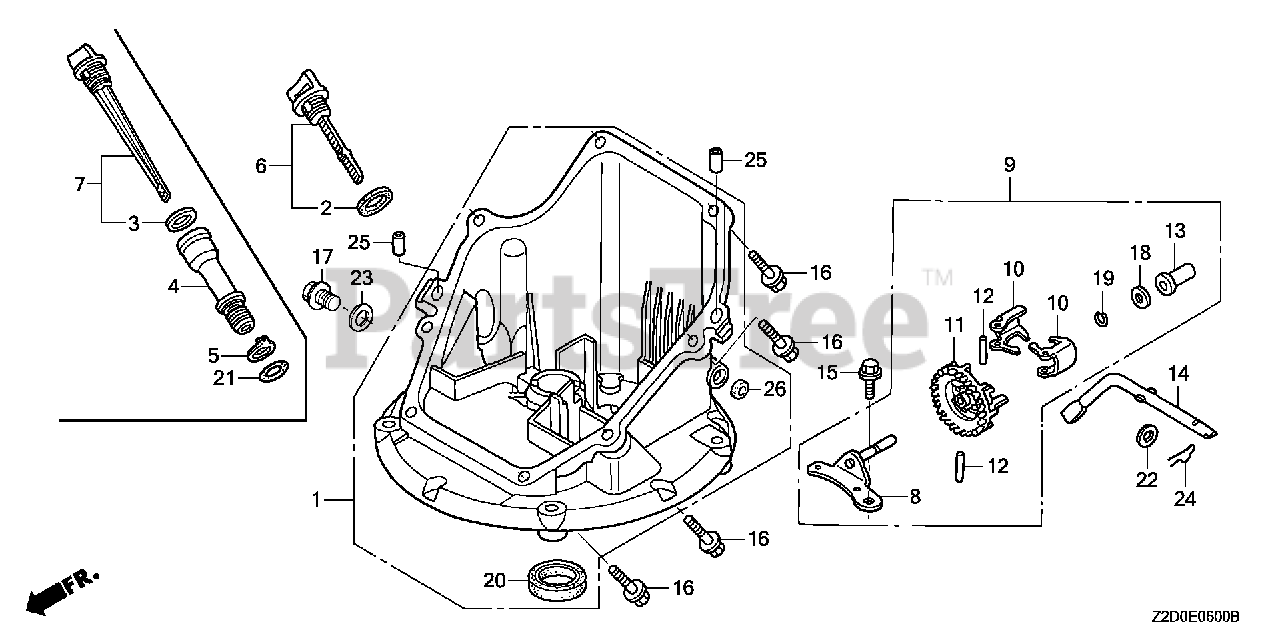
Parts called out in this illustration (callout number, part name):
1	PAN ASSY., OIL
2	GASKET, OIL FILLER CAP
6	GAUGE ASSY., OIL LEVEL
8	SHAFT, GOVERNOR HOLDER
9	GOVERNOR ASSY.
10	WEIGHT, GOVERNOR
11	HOLDER, GOVERNOR WEIGHT
12	PIN, GOVERNOR WEIGHT
13	SLIDER, GOVERNOR
14	SHAFT, GOVERNOR ARM
15	BOLT, FLANGE (6X14) (CT200)
16	BOLT, FLANGE (6X25) (CT200)
18	WASHER, THRUST (6MM)
19	CLIP, GOVERNOR HOLDER
20	OIL SEAL (28X41.25X6)
22	WASHER, PLAIN (6MM)
24	PIN, LOCK (8MM)
25	PIN, DOWEL (8X20)
